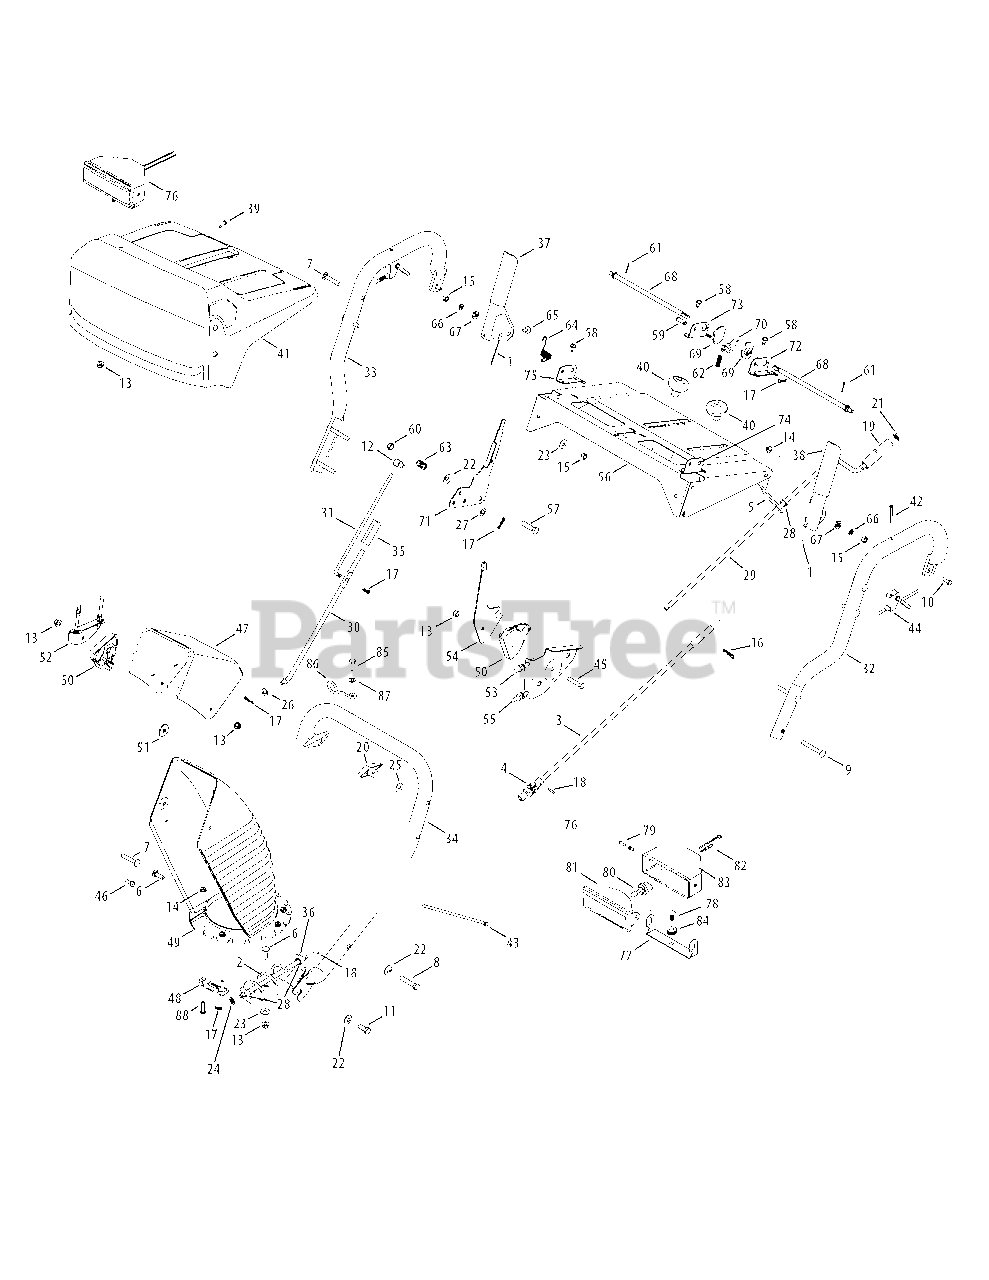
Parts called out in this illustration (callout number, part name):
1	Cable Ass’y, Auger/Drive
2	Chute Crank Assembly
3	Chute Crank Rod Assembly
4	Joint Block Assembly
5	Chute Crank Bracket
6	Carriage Screw, 5/16-18 x 1.0
7	Carriage Screw, 5/16-18 x 1.75
8	Hex Screw, 3/8-16 x 2.00
9	Carriage Screw, 5/16-18 x 2.5
10	Hex Screw, 1/4-20 x .75
11	Screw, Hex, 3/8-16 x 1.00
12	Ferrule, 5/16-18 x .312 Dia
13	Flange Lock Nut 5/16-18
14	Flange Lock Nut 1/4-20
15	Hex Lock Nut, 5/16-18 GR5
16	Internal Cotter Pin
17	Internal Cotter Pin
18	Spring Pin, .156 dia. x .875 Lg.
19	Knob, Crank
20	Wing Knob, 5/16-18
21	Push Cap, 3/8
22	Bell Wash, .375 x .87 x .063
23	Flat Washer, .349 x .879 x .063
24	Flat Wash, .375 x .738 x .063
25	Wash, Bell, .34 x .872 x .06
26	Flat Wash, .344 x .688 x .065
27	Flat Washer, .344 x .750 x .120
28	Plastic Bushing, .38 ID
29	Upper Chute Crank Rod
30	Lower Shift Rod
31	Upper Shift Rod
32	Handle, Upper LH
33	Handle, Upper RH
34	Handle, Lower
35	Shift Rod Connector
36	Chute Crank Bracket
37	Engagement Handle, RH
38	Engagement Handle, LH
39	Screw, #10-16 x .625
40	Shift Knob
41	Handle Panel, 3-Style
42	Screw, #10-24 x 1.75
43	Cable Tie
44	Trigger Control
45	Hex Screw 5/16-18 x 1.5
46	Hex Screw, 1/4-15 x .75
47	Upper Chute, 6.0
48	Chute Flange Keeper
49	Lower Chute
50	Cbl. Guide, Chute Tilt
51	Flat Wash, .344 x 1.125 x .12
52	Cable Bracket
53	Chute Control Cable, 66"
54	Chute Tilt Handle
55	Chute Control Cable w/Clip
56	Handle Panel
57	Hex Screw, 3/8-24 x 1.5
58	Hex Screw, 1/4-20 x .5
59	Clevis Pin, .312 x 1.0
60	Insert Nut, 3/8-24
61	Cotter Pin, 3/32 x .75
62	Compression Spring
63	Compression Spring
64	Torsion Spring
65	Rubber Bumper
66	Lock Washer, 5/16
67	Flat Wash, .35 Sq x .72 x .134
69	Handle Lock Cam
70	Handle Lock Pawl
72	Handle Support Bracket - LH
73	Handle Support Bracket - RH
74	Handle Support Bracket - RH
76	Light Assembly
77	Lamp Mount Bracket
78	Carriage Bolt, 5/16-18 x .750
79	Screw, M4 x .7
81	Lamp Housing
85	Hex Head Screw, MB-1.25 x 20
86	Cable Guide
87	Flat Washer, .330 x .630 x .0635
88	Hex Screw 1/4-20 x 1.0
